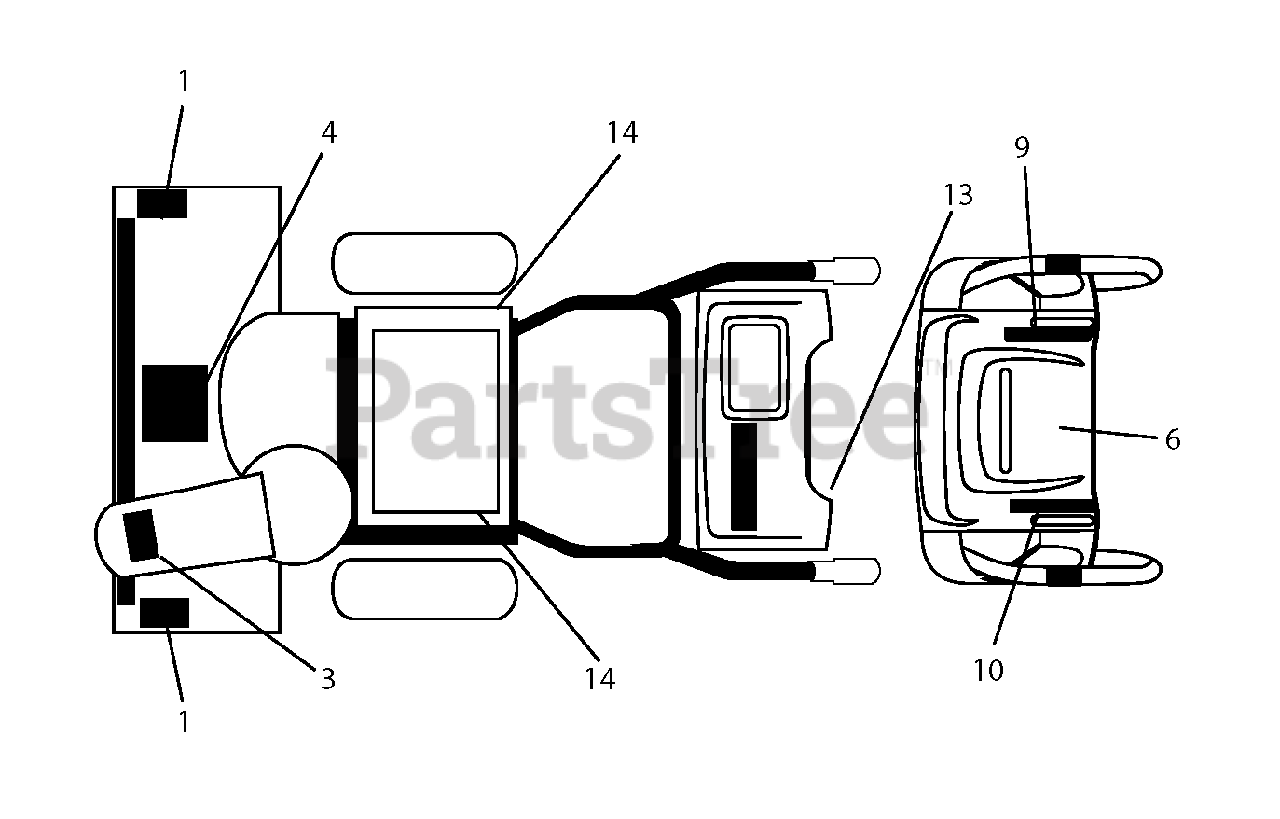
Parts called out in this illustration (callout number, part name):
1	DECAL.AUGER.SAFETY.
3	DECAL.CHUTE.SAFETY.
4	DECAL.AUGER."
6	DECAL.CONSOLE.INSTRUCTION
9	DECAL.CONS.RT.SPD/LEV/PWRST
13	DECAL.FENDER
14	DECAL.BELT.GUARD.
